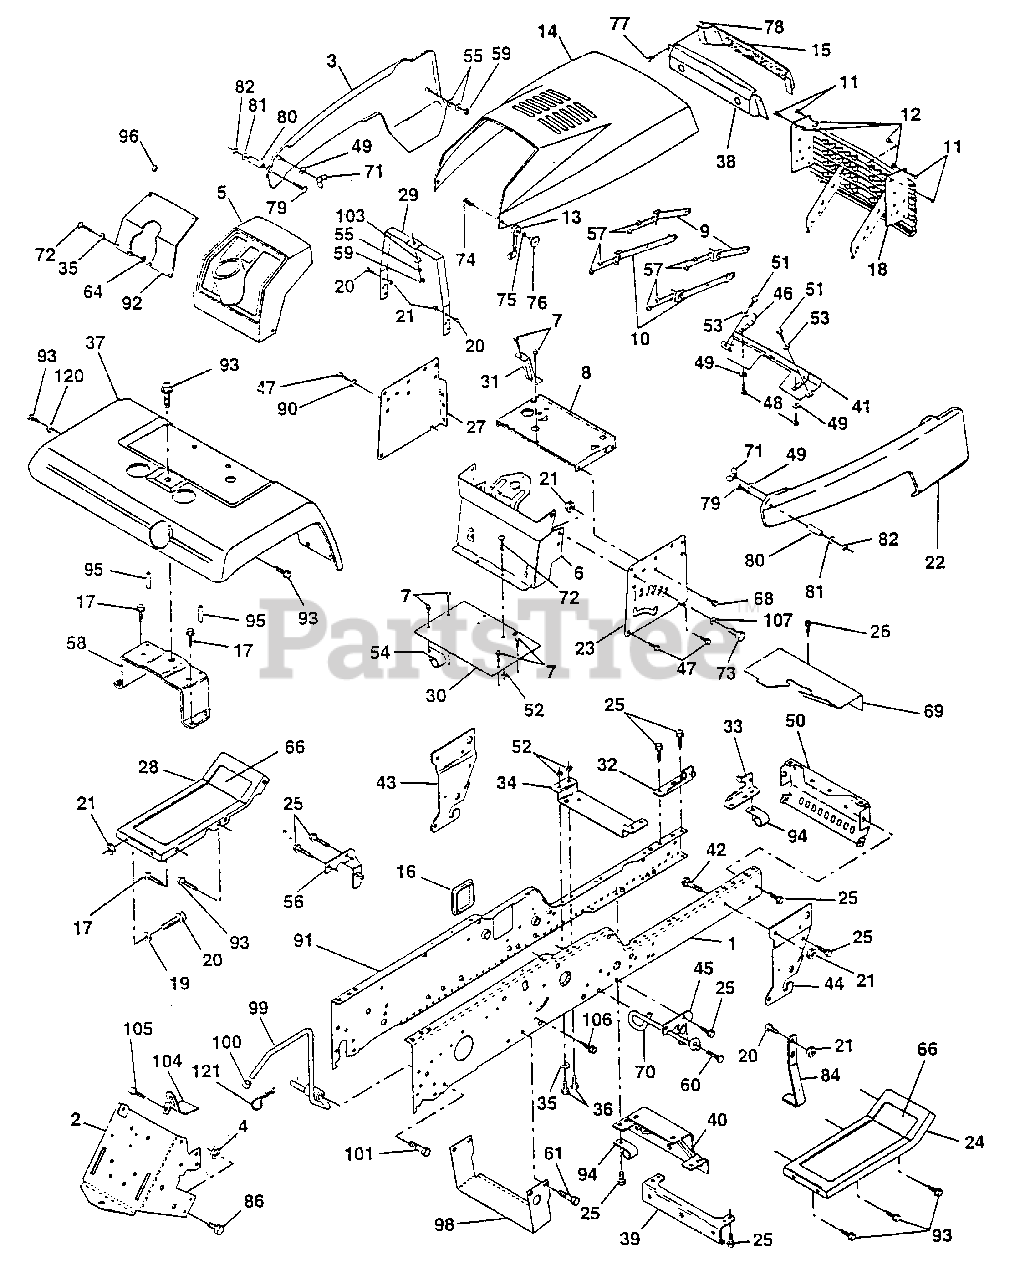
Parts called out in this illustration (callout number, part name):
1	Rail, Frame RH
2	Drawbar, Gt
3	Panel Asm., Side LH
4	Nut, Lock Hex 7/16 Unc
5	Dash, Plastic Black
6	Dash Asm., Lower
7	Screw, Thd Cut 1/4-20 x 1/2
8	Support, Battery
9	Strap, Asm. Hinge Front
10	Strap, Asm. Hinge Rear
11	Bolt Shoulder 1/4-20
12	Nut Crownlock 1/4-20
13	Latch, Chute Blk
14	Hood Asm., Pnt
15	Lens, Headlight Bar
16	Cover, Access
17	Screw, Thdrol 3/8-16 x 3/4
19	Washer 13/32 x 13/16 x 12 Ga.
20	Bolt, Fin Hex 3/8-16 x 1
21	Nut, Lock Hex W/Wsh 3/8-16 Unc
22	Panel Asm., Side RH
23	Panel, Dash Side RH
25	Screw, Thdrol 3/8-16 x 3/4
26	Screw, Thdrol 5/16-18 x 3/4
27	Panel, Dash Side LH
29	Bracket, Support Dash
31	Brace, Support Steering
32	Bracket Asm., Frame Pivot Lh
33	Bracket Asm., Frame Pivot Rh
34	Bracket, Engine Support Rear
35	Washer 11/32 x 11/16 x 16 Ga.
36	Bolt, Fin Hex 5/16-18 x 3/4
38	Beze. Asem.
39	Bracket, Axle Front
40	Bracket, Support Axle/Engine
41	Strap, Grille
42	Bolt, Carriage 3/8-16 x 1
43	Bracket, Spnsn Front Lh
44	Bracket, Spnsn Front Rh
45	Bracket Asm., Susp Chassis Rh
46	Bracket Brille
47	Screw Thdrol 3/8-16 x 1/2
48	Screw Thdrol 5/16 - 18 x 3/4
49	Washer 13/32 x 3/4 x 10 Ga
50	Bracket, Chassis Front
51	Screw Hex Wsh Thdrol 1/4 - 20 x 3/4
52	Locknut, Hex W/Ins 5/16-18 Unc
53	Washer 9/32 x 5/8 x 16 Ga
54	Clip, Insulated
55	Washer 9/32 x 3/4 x 16 Ga.
56	Bracket Asm., Susp Chassis Lh
57	Nut Keps Hex 1/4-20
58	Bracket Asm., Fender
59	Nut, Fin Hex 1/4-20
60	Screw Thdrol 3/8-16 x 1-1/4
61	Screw Thdrol. 3/8-16 x 3/4
62	Retainer Spring
64	Nut 5/16-18
66	Pad, Footrest
68	Screw, Thdrol 5/16-18 x 1/2
70	Guide, Belt Mid Span
71	Nut, Plastic Locking Wing 1/4-20
72	Screw, Mach Trhd 5/16-18 x 3/4
73	Bolt, Fin Hex 3/8-16 x 1 Gr. 5
74	Screw, Machine #10-24
75	Washer, Lock #10
76	Nut, Weld #10-24
77	Screw Hex Whd Tap #10 - 16 x 5/8
79	Screw, Machine #10-24 x 1/4
80	Spacer, Split
81	Washer 7/32 x 1/2 x 18 Ga.
82	Nut #10-24
84	Stop, Over Center Mower
86	Bolt, Fin Hex 7/16-14 Unc x 1
90	Washer, Lock External Tooth 3/8
91	Rail, Frame Lh
92	Plate, Silkscreen Dash
93	Screw, Thdrol 3/8-16 x 1/2
94	Clip, Fuel Line
95	Push Nut, Nylon
96	Plug, Hole
98	Bracket Chassis Skid
99	Rod Asm. Bypass
100	Cap Brake Parking Red
101	Screw Thdrol. 3/8-16 x 1-3/4
103	Washer, Lock 1/4
104	Bracket Lock Bypass
105	Screw Thdrol. 5/16-18 x 1/2
106	Screw Thdrol. 5/16-18 x 1.25
107	Washer 13/32 x 1 x 14 Ga.
120	Washer 13/32 x 1 x 16 Ga.
